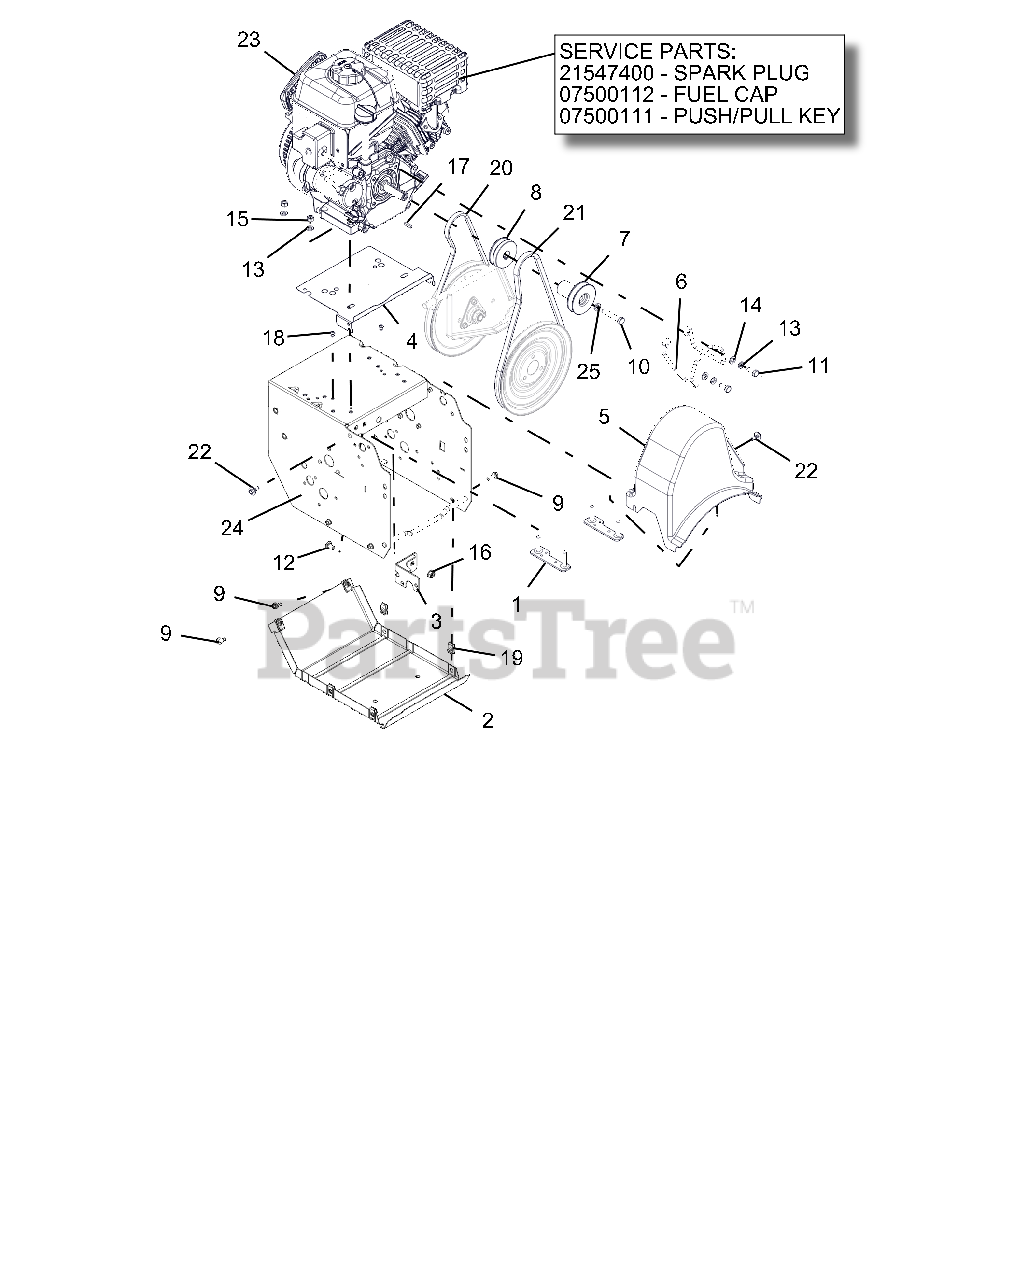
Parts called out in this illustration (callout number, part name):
1	STRAP, ENGINE BOLT-WELDMENT
2	COVER, BOTTOM
3	WELDMENT, FRAME BRACKET
4	BAFFLE,ENGINE,SMALL BLOCK
5	COVER, COMPACT BELT
6	FINGER, BELT
7	SHEAVE,AUGER 3/4" PM
8	SHEAVE, TRACTION-COMPACT TRACK
9	BLT-HEX .25-20X.75 HWH YZ GR5
10	BLT-HEX .38-24X2.0 YWZC
11	BLT-HEX .31-24X.75 YWZC GR5
12	@BLT-RHDSSQNK .31-18X.62 G5YZ
13	WSHR-LK .312X.097 HVY YWZC
14	@WSHR-FL-STL.344X.688X.065YWZC
15	@NUT-HEX .31-18 YWZC
16	@NUT-LK-TOP-FLG .31-18 YWZC
17	KEY-SQ .188X.75X.188
18	RVT-POP .187 YZ
19	NUT-RTNR .25-20X.56
20	V-BELT, 3L-WRAPPED
21	V-BELT, HA-RAW EDGE
22	SCR-TAP .25-20X.5 CAPTIVE
23	ENGINE, ARIENS AX208 240V/60W
23	PLUG, SPARK
23	CAP, FUEL TANK BLACK
23	KEY, PUSH/PULL LCT (2/PACKAGE)
24	FRAME, 920/921
25	@WSHR-LK .38X.094 REG YWZC
